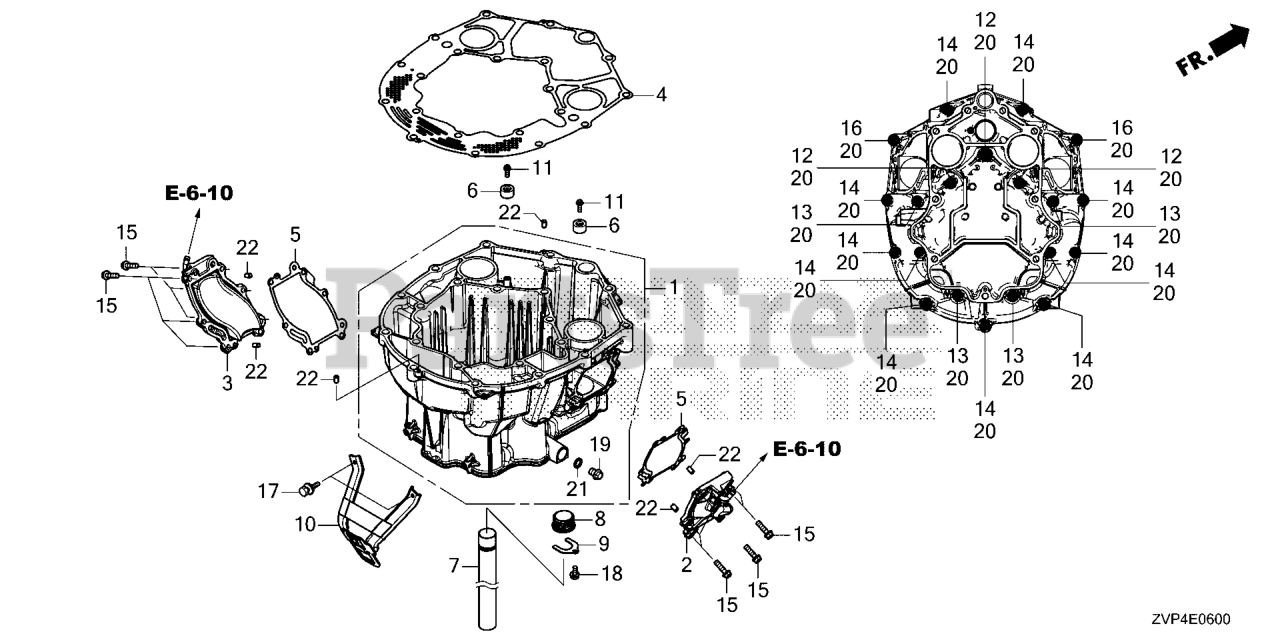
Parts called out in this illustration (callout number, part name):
1	CASE ASSY., OIL
2	COVER COMP
3	COVER COMP
4	PKG, OIL PAN
5	GSKT, OIL CASE COVER
6	METAL, ANODE
7	TUBE, WATER XL
8	GROMMET, WATER TUBE
9	PLATE, WATER TUBE
10	BRACKET, RR. (LOWER)
11	BOLT, FLANGE (6X18)
12	BOLT, HEX. (12X175)
13	BOLT, HEX. (12X120)
14	BOLT, HEX. (12X50)
15	BOLT, FLANGE (8X30)
16	BOLT, HEX. (12X80)
17	BOLT-WASHER (6X16)
18	BOLT, FLANGE (6X12) Use from Frame SN 1005249.
19	BOLT, DRAIN PLUG
20	WASHER, PLAIN (12MM)
21	WASHER, DRAIN PLUG (12MM)
22	PIN A, DOWEL (6X10)
